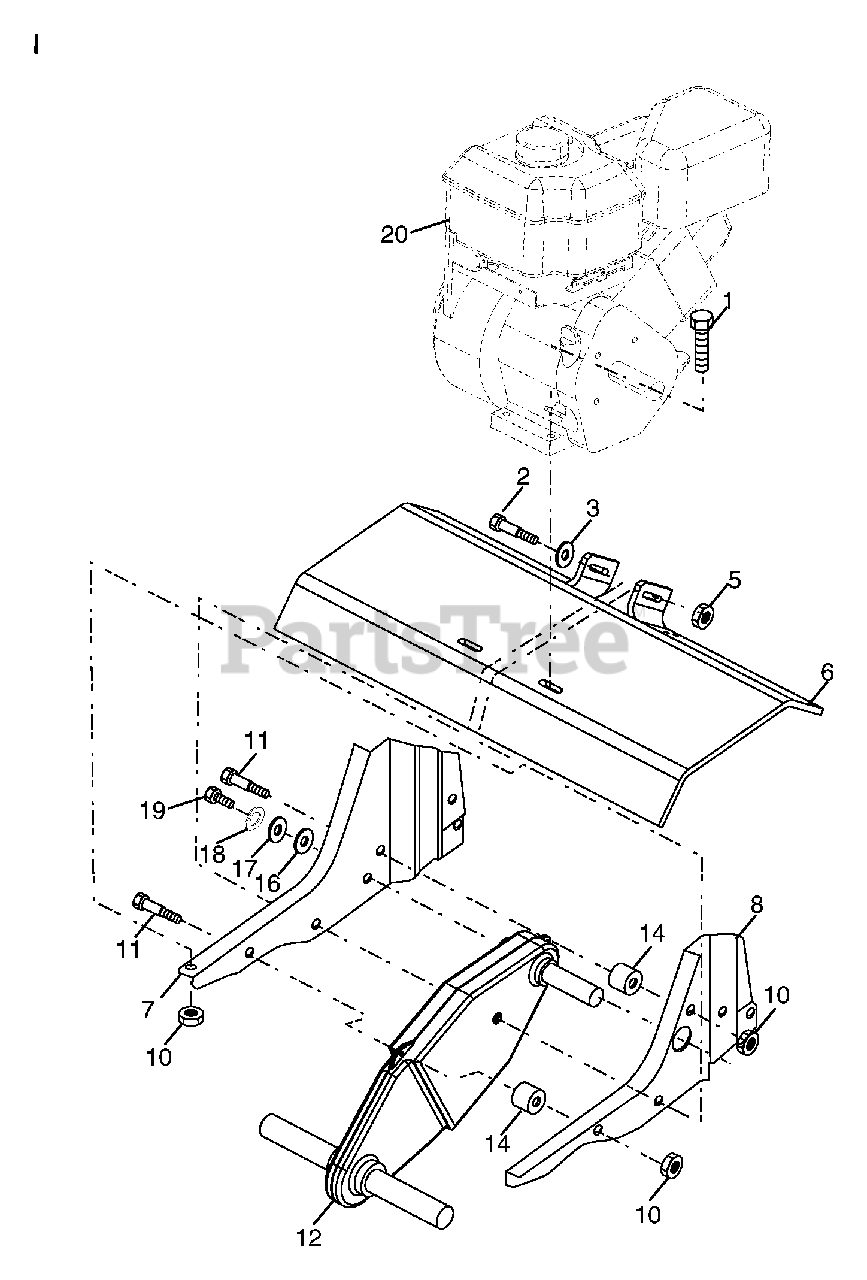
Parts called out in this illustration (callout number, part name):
1	Bolt, Hex 5/16-18 x 1-1/2 Gr. 2
2	Bolt, Hex, Fin 3/8-16 x 3-1/4
3	Washer 13/32 x 13/16 x 11
5	Nut Lock Flg 3/8-16 unc
6	Shield, Tine
7	Bracket, Engine, R.H.
8	Bracket, Engine, L.H.
10	Nut Lock Hex Flg
11	Bolt, Shoulder
12	Transmission
14	Spacer, Split
16	Washer 9/32 x 7/8 x 12 Ga.
17	Washer 9/32 x 1-1/4 x 16 Ga.
18	Washer, Lock 1/4
19	Bolt, Hex 1/4-28 x 3/4 Gr. 5
